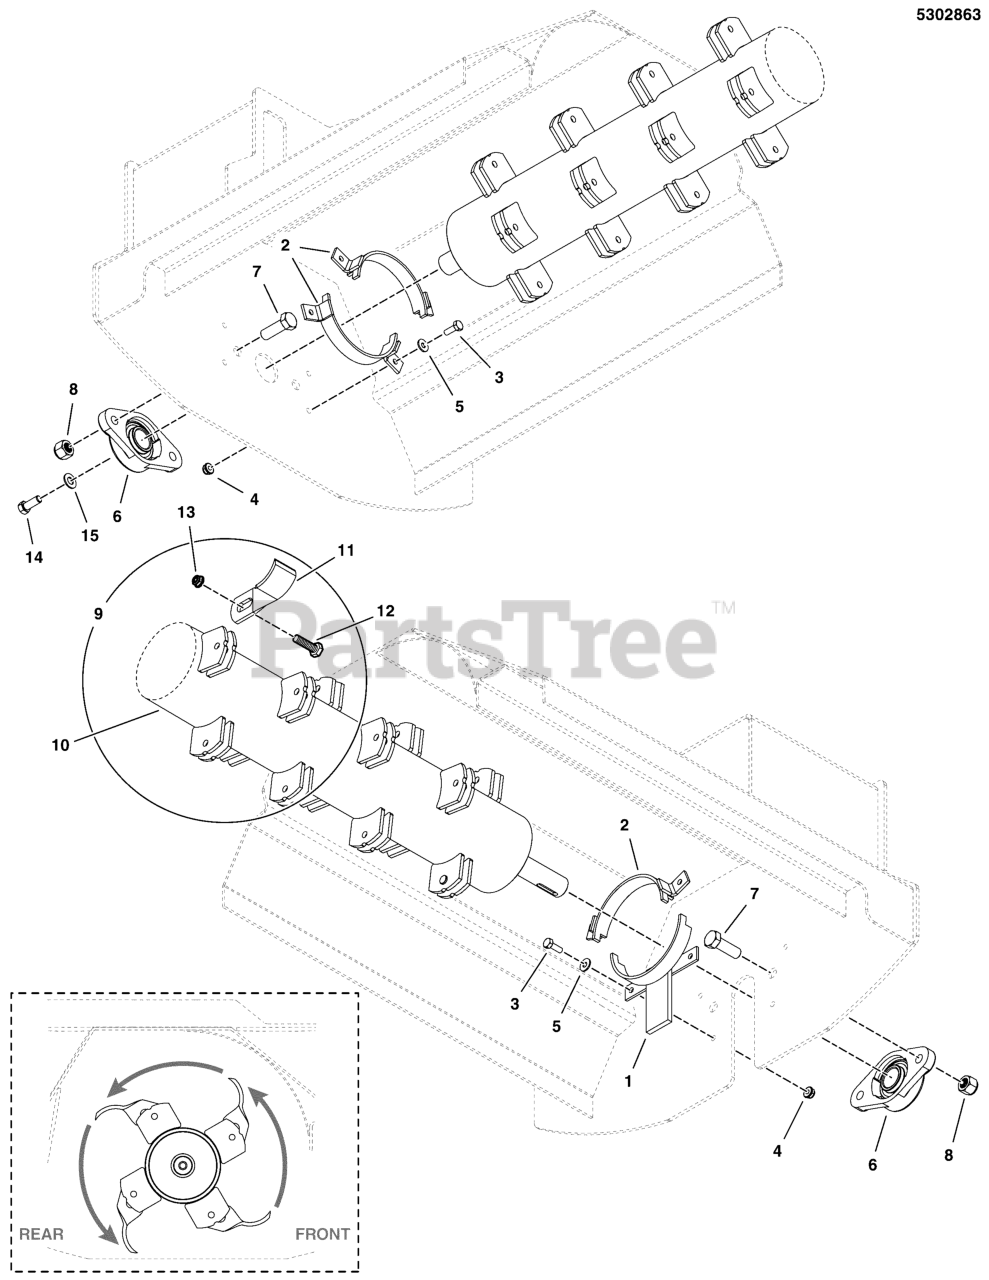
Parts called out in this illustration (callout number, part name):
1	WELD, ROTOR GUARD, LH BTM - BLK
2	WELD, ROTOR GUARD - BLK
3	BOLT, 1/4-20 X 3/4 GD5 YZ
4	NUT, 1/4-20 HEX NYLOCK FLANGE
5	WASHER, 1/4 SAE
6	BEARING, 2 BOLT FLANGE, 1", CAST
6	BEARING, 2-BOLT FLANGE, 25MM
7	BOLT, 1/2-13 X 1-1/2 GD5 CZ
8	NUT, 1/2-13 HEX NYLON LOCK
9	48" ROTOR ASM. & BAL, FLAIL
9	ROTOR ASSM, 48, FLAIL
10	48" ROTOR
11	CUTTER, FLAIL, 1-3/8 X 3.0, FINISH
12	BOLT, 3/8-16 X 1-1/4" GD5 CZ
13	NUT, 3/8-16 HEX SIDE LOCK
14	BOLT, 3/8-16 X 3/4, PLT W/PATCH
14	BOLT, M12 X 1.75 X 25MM, CZ
15	WASHER, .390 X 1.50 X .109, YZ
15	WASHER, .53 X 1.50 X .25
